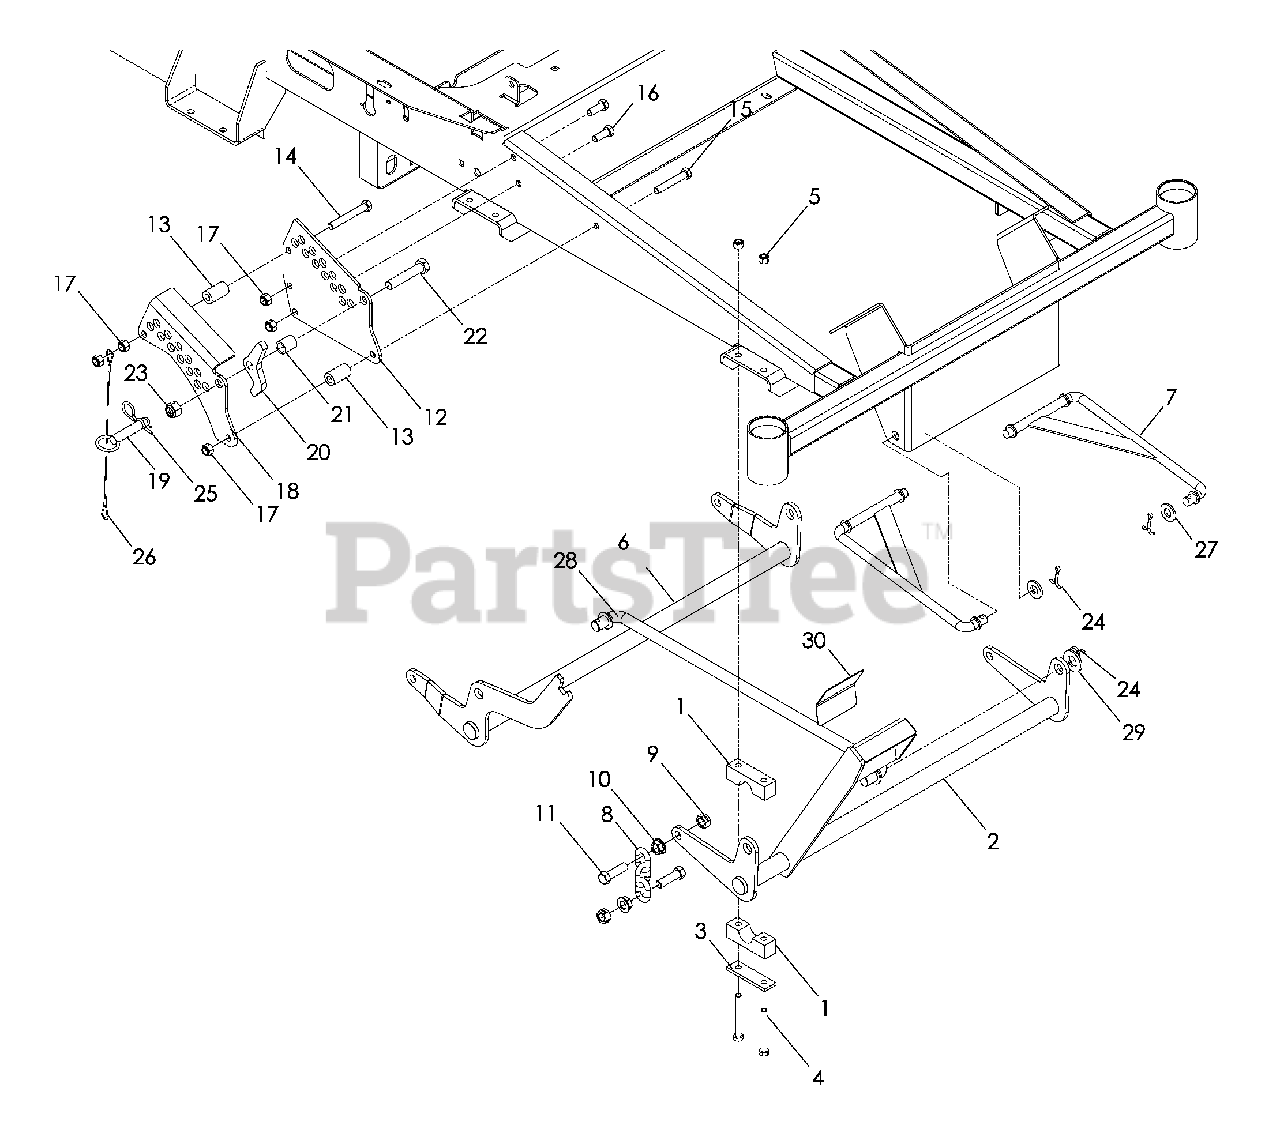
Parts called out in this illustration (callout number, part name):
1	PILLOW BLOCK
2	FRONT LIFT SHAFT
3	REINFORCEMENT BAR
4	HCS 5/16-18 x 2¾
5	NUT 5/16-18 NYLOC
6	REAR LIFT SHAFT
7	STRUT LINKAGE
8	LIFT CHAIN, 3 LINKS
9	NUT 7/16-14 CENTERLOCK
10	NUT 7/16-14 WHIZLK
11	HCS 7/16-14 x 1½
12	HEIGHT ADJUST PLATE
14	HCS 3/8-16 x 2¾
15	HCS 3/8-16 x 2¼
16	HCS 3/8-16 x 1
17	NUT 3/8-16 NYLOC
18	HT ADJ PLATE, OUTER
20	PAWL, STOP
22	HCS ½-13 x 2½
23	NUT ½-13 NYLOC
24	COTTER PIN, 5/32 x 1¼
25	HAIRPIN, #4
27	WASHER ½ SAE
28	DECK LIFT LINK
29	WASHER 5/8 SAE
30	ANTI-SKID PAD
